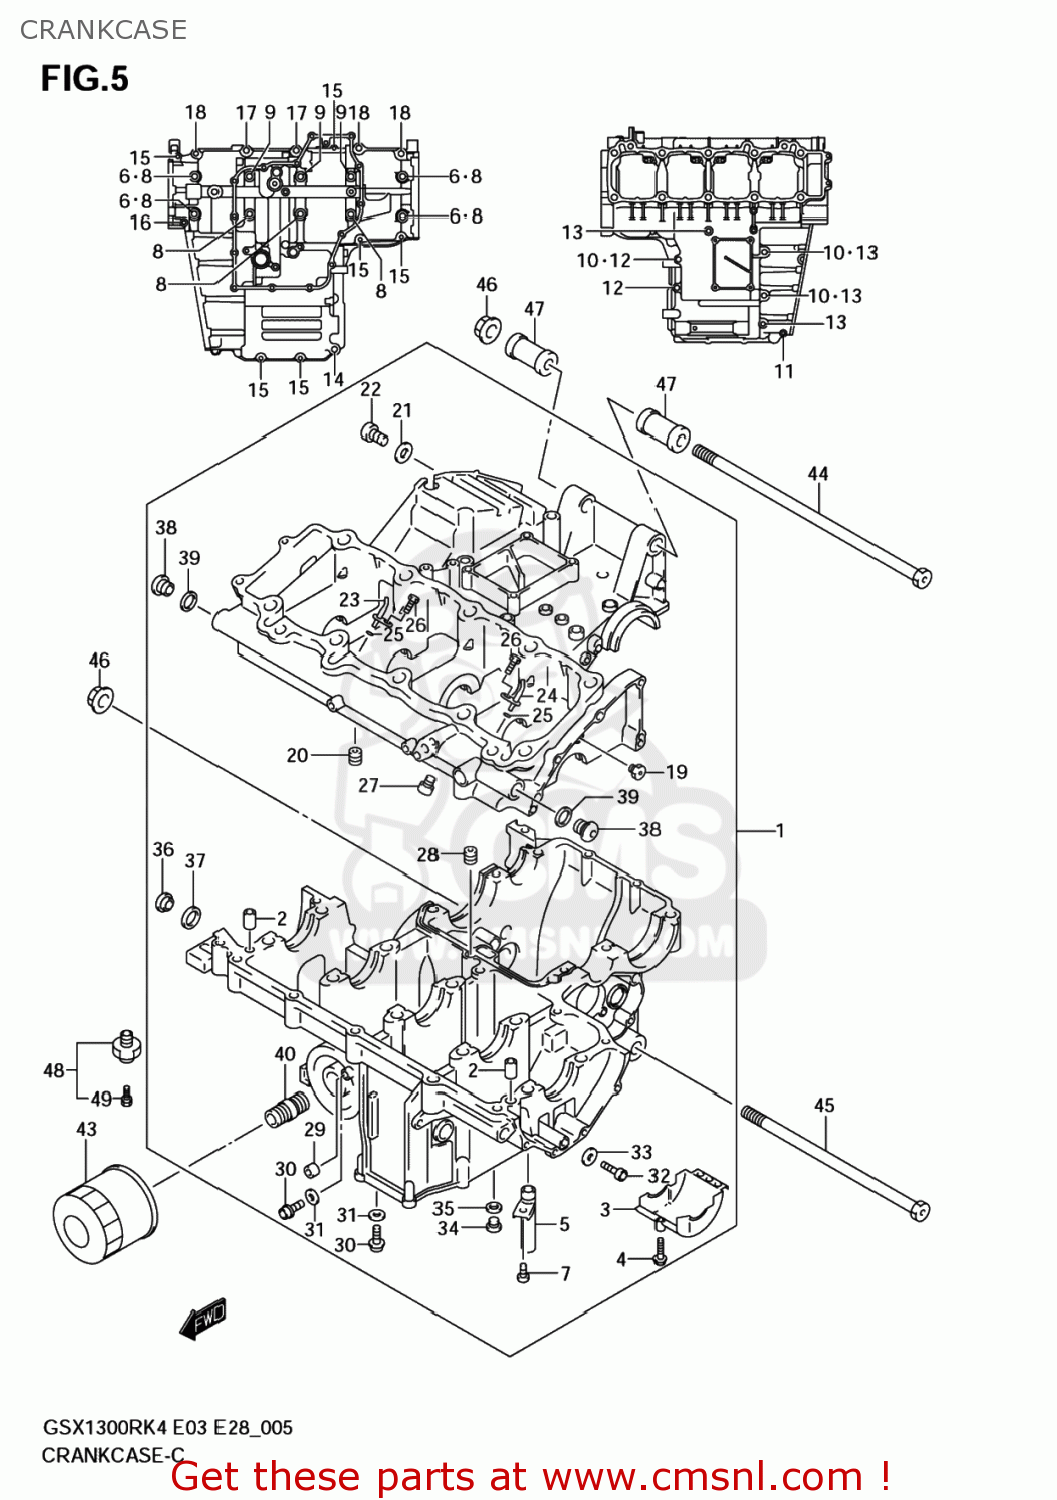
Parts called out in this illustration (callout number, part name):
1	CRANKCASE SET
2	PIN,CRANKCASE
3	SEPARATOR,OIL
4	SCREW
5	UNION,BREATHER
6	GASKET(10.2X20X2).3 (NAS)
7	BOLT
8	BOLT(9X95)
9	BOLT(9X115)
10	GASKET(8.2X14X1) (NAS)
11	BOLT
12	BOLT
13	BOLT (8X80)
14	BOLT
15	BOLT
16	BOLT
17	BOLT(8X60)
18	BOLT(8X50)
19	JET,MAGNETO COOLING
20	JET,AIR(100)
21	GASKET(5.8X13X1.2) (NAS)
22	BOLT
23	JET,PISTON COOLINGR
24	JET,PISTON COOLING
25	O RING(D:1.2,ID:4)
26	BOLT(6X12)
27	BOLT(6X10)
28	JET,AIR(180)
29	JET,OIL PAN GALLERY
30	BOLT
31	GASKET(5.8X13X1.2) (NAS)
32	BOLT
33	GASKET(8.2X14X1) (NAS)
34	PLUG(10X10)
35	GASKET(10X14X3.6) (NAS)
36	PLUG,16X8
37	GASKET(16X22X2) (NAS)
38	PLUG,14X12
39	GASKET(13.8X18.8X4.8) (NAS)
40	UNION,OIL STAND
41	BEARING,CRANK THRUST,L
42	BEARING,CRANK THRUST,L
43	FILTER ASSY,EN
44	BOLT(12X320)
45	BOLT(12X243)
46	NUT
47	SPACER,ENG MTG(L47)
48	SWITCH ASSY,OIL PRESSURE
49	BOLT,OIL PRESSURE SWITCH
